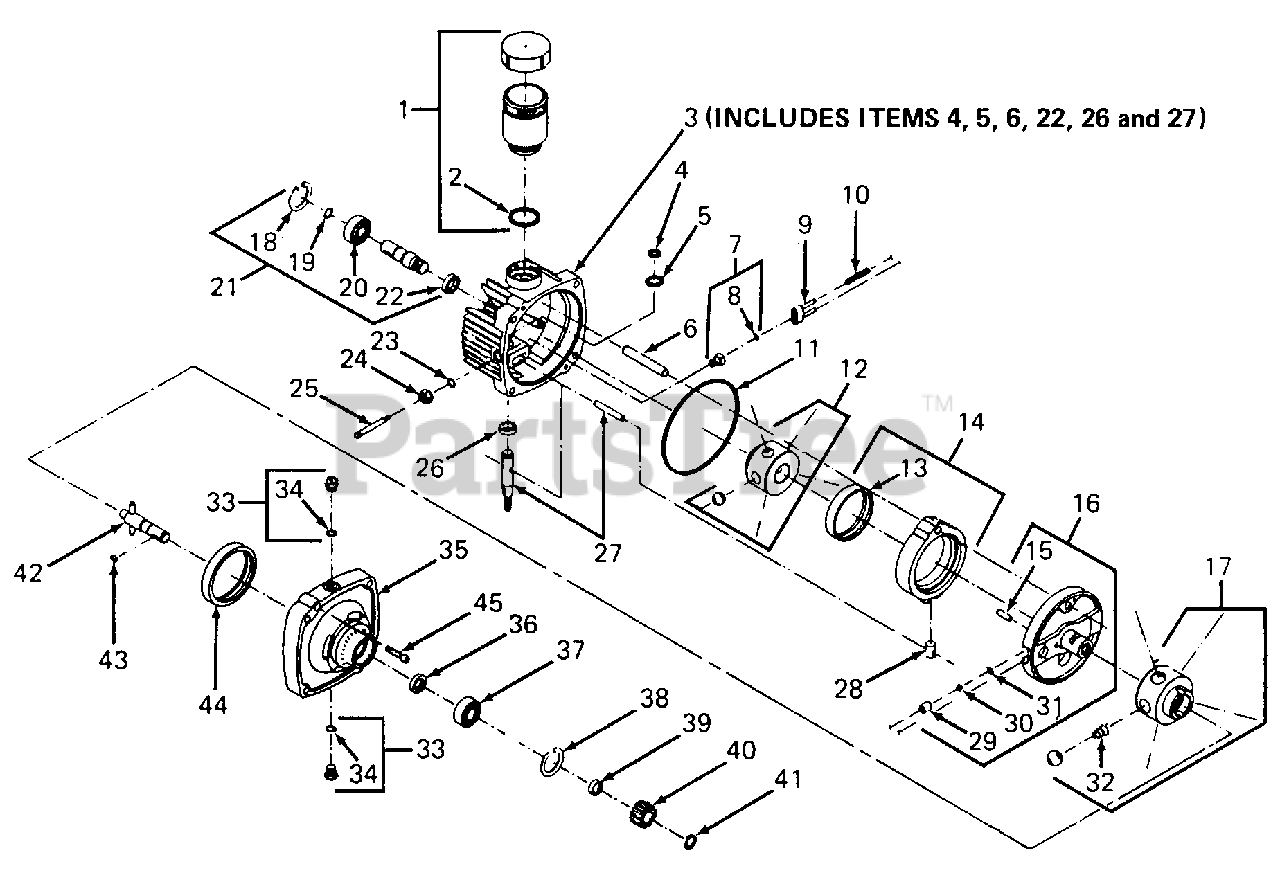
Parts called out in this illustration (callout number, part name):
1	Reservoir Kit
2	Ring, Square Cut Seal
3	Cover Service Kit
4	Ring, External Retaining
5	Washer, Control Shaft
6	Dowel, Pivot Pin
7	O-Ring Fitting Guide Kit,
10	Spring, Valve
11	Ring, Square Cut Seal
12	Pump Rotor Ball Kit
15	Pin, Coil, 5/16 Dia X 3/4 Long
16	Pintle Kit
17	Motor Rotor Ball Kit,
18	Ring, Retaining
20	Bearing, Ball
21	Kit, Input Shaft
22	Seal, Oil
25	Shaft, Dump Valve
26	Seal, Oil
27	Kit, Control Shaft
28	Insert, Cam Ring
29	Body, Check Valve
30	Ball, 5/16 Dia
31	Ring, Retaining
32	Spring, Piston
33	O-Ring Plug Kit,
36	Seal, Oil
37	Bearing, Ball
38	Ring, Retaining
41	Ring, External Retaining
42	Output Shaft Kit
43	Key, Woodruff
45	Screw, Socket Head Cap
